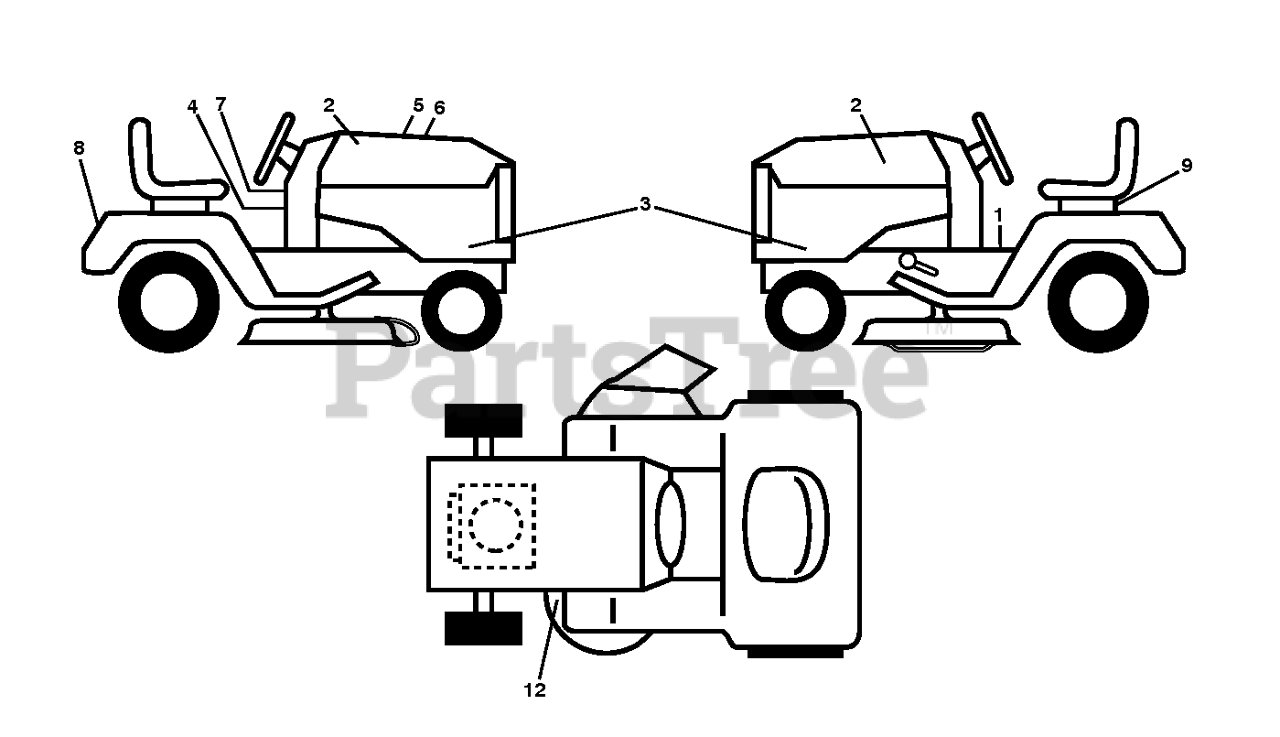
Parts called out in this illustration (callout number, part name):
1	DECAL.WARN.START.INSTRUCTIONS
2	DECAL.BADGE.170MM.TEXTLOGO.
3	RP DECAL.PNL.SD.YTH21K46.HUSQ
4	DECAL, WARNING SPARK ARRESTOR
5	DECAL.WARNING.CUST.RESP.E85.
6	DECAL.REPLACEMENT.960450026
7	LABEL.EMISS.CA.HUSQ/LOWES.2011
8	DECAL.FENDER
9	DECAL BTRY SYMBOLS
12	DECAL V BELT SCHEMATIC
